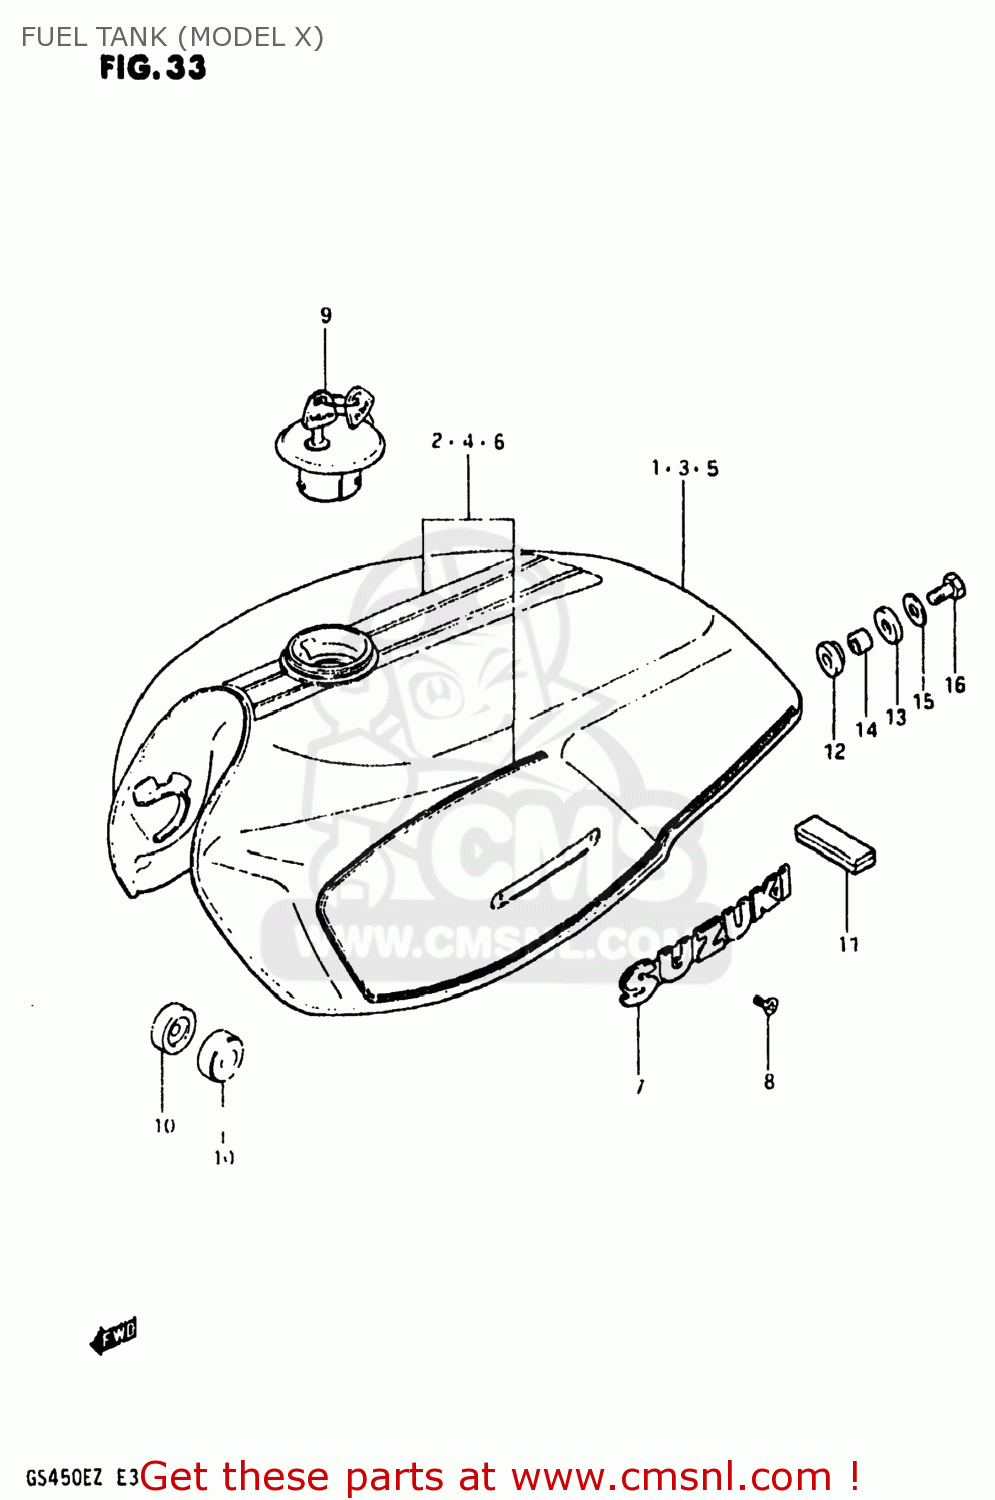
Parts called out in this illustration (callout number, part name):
1	TANK ASSEMBLY,FUEL
2	TAPE SET,FUEL TANK
3	TANK ASSEMBLY,FUEL
4	TAPE SET,FUEL TANK
5	TANK ASSEMBLY,FUEL
6	TAPE SET,FUEL TANK
7	EMBLEM,FUEL TANK
8	SCREW 3X6
9	CAP SET,FUEL TANK
10	CUSHION
11	CUSHION
12	CUSHION
13	CUSHION
14	SPACER(8.5X12X19)
15	WASHER (8.5X29X1.6)
16	BOLT (8X30)
